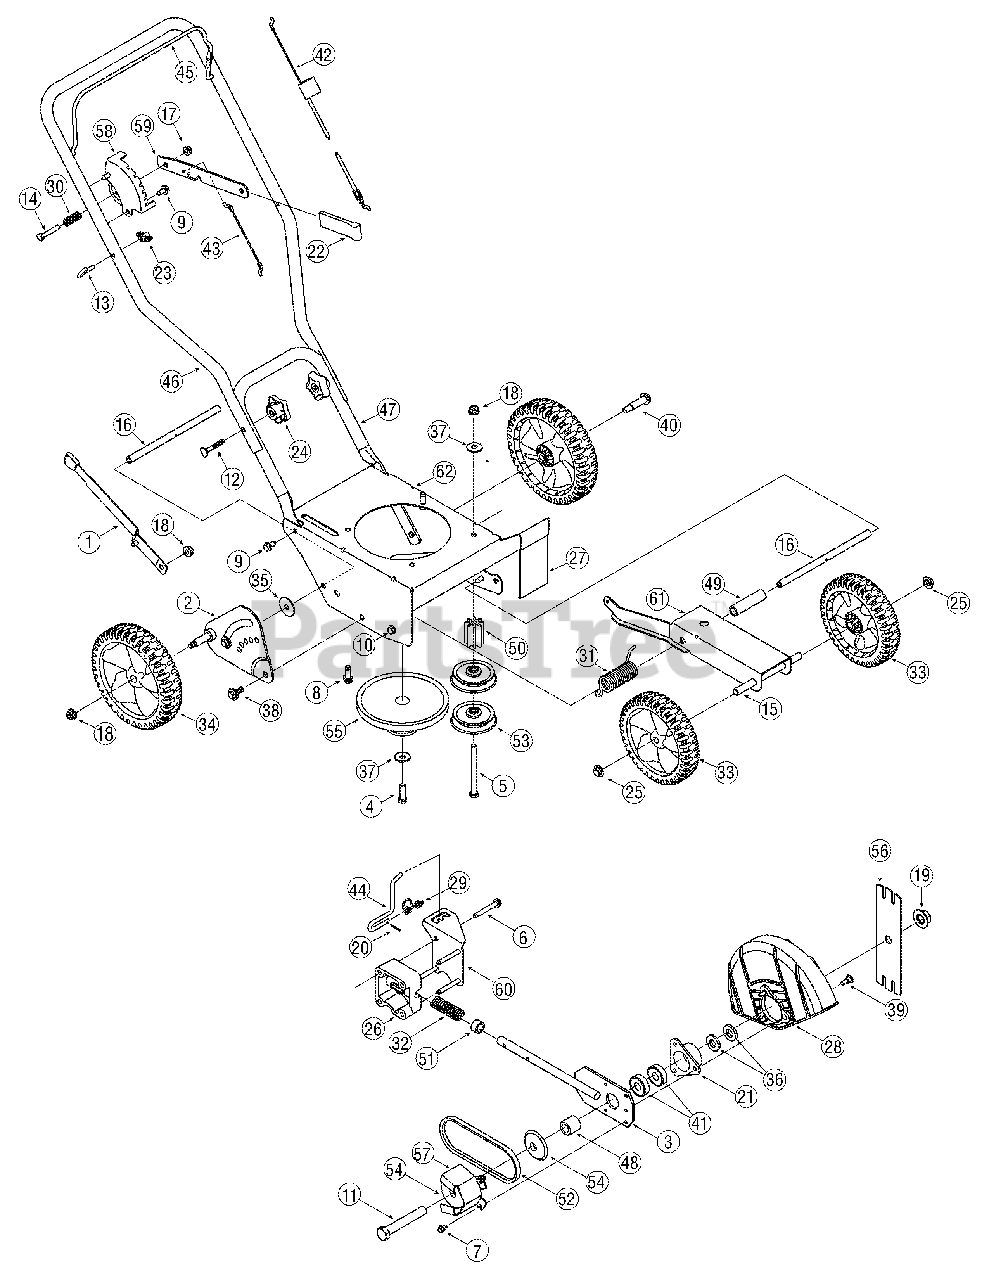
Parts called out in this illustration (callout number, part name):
1	Curb Height Adjustment Lever
2	Curb Height Adjuster Plate
3	Blade Plate Assembly
4	Screw 3/8-24
5	Screw 3/8-16
6	Hex Screw, 5/16-18
7	Self-tapping Screw, 1/4-20
8	Screw, 3/8-16
9	Hex Screw, 5/16-12
10	Hex Screw 5/16-18
11	Hex Screw, 5/8-18
12	Carriage Bolt, 5/16-18
13	Rope Guide (Eye Bolt)
14	Hex Screw, 5/16-18
15	Axle Shaft .50x6.65
16	Frame Spacer .50x9.25
17	Lock Flange Nut, 5/16-18
18	Flange Nut 3/8-16
19	Flange Nut, 5/8-18
20	Clevis Pin 3/32 x .625
21	Bearing Cup
23	Wing Nut
24	Star Knob
25	Push Cap 1/2" rod
26	Bearing Block
27	Debris Guard
28	Blade Guard
29	Double Torsion Spring
30	Compression Spring
31	Torsion Spring
32	Compression Spring
33	Wheel 7 x 1.8 Spoke Bar Grey
34	Wheel 8 x 1.8 Spoke Bar Grey
35	Flat Washer, .385 x 1.5 x .075
36	Flat Washer .635x1.24x.181
37	Bell Washer,.396 x 1.140
38	Shoulder Screw, 3/8-16
39	Shoulder Screw
40	Shoulder Screw, 3/8-16
41	Bearing, .625 ID x 1.57 OD
42	Control Cable (Tecumseh)
43	Wheel Adjustment Cable
44	Blade Adjustment Rod
48	Spacer, .63 x 1.12 x 1.06
49	Spacer
50	Pulley Mount Spacer
51	Spacer, .64 x.88 x .50
52	Belt
53	Flat Idler Pulley, 2.5 OD
54	Sheave
55	Combination Flywheel Pulley
